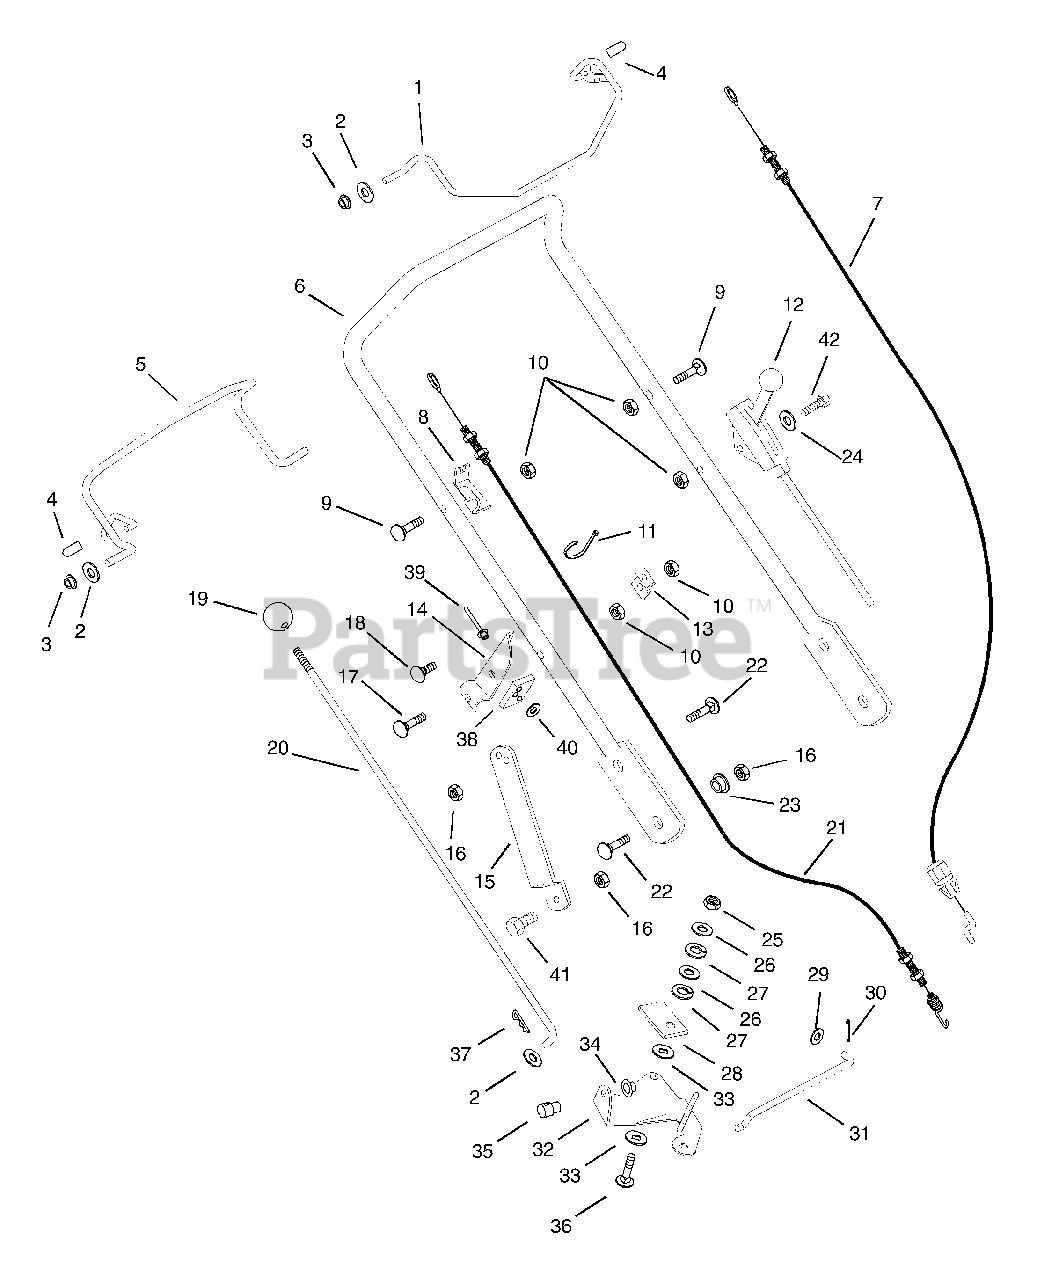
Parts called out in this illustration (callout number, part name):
1	Engine Bail Weldment
2	Washer-Flat Steel .344 x .688 x .065
3	Bushing-Flange .325 x .688 x .560
4	Cap, Vinyl .25 I.D.
5	Traction Bail
6	Handlebar
7	Engine Control Cable
8	Cable Anchor-Right Hand
8	Cable Anchor-Left Hand
9	Bolt-Round Head Square Neck .25-20 x 1.25
10	Nut-Locking-Center .25-20
11	Cable Tie
12	Throttle Cable
13	Brace-Speed Control
14	Bracket-Speed Control
15	Handlebar Bracket
16	Nut-Locking-Center .31-18
17	Bolt-Round Head Square Neck .25-20 x 1.38
18	Bolt-Round Head Square Neck .25-20 x .50
20	Rod-Speed Control
21	Traction Cable
22	Bolt-Round Head Square Neck .31-18 x 1.00 Grade 5
23	Shoulder Spacer
24	Washer-Flat-Steel .250 x .562 x .049
25	Nut-Locking-Center .38-16
26	Washer-Flat-Steel .406 x .812 x .065
27	Washer-Lock .375 x .115 Heavy
28	Pressure Flange
29	Washer-Flat-Steel .281 x .620 x .065
30	Pin-Cotter .06 x .50
31	Shift Link
32	Bell Crank-Speed Control
33	Friction Washer
34	Cap, .38 Rod
36	Bolt-Round Head Square Neck .38-16 x 1.50
37	Pin-Hair-Internal .08 x .18 x 1.18
38	Support Pad
39	Rivet .187 x .575
40	Washer-Flat Steel .219 x .50 x .049
41	Bolt-Hex .31-18 x .75 Grade 5
42	Bolt-Hex .250-20 x 1.75 Grade 5
